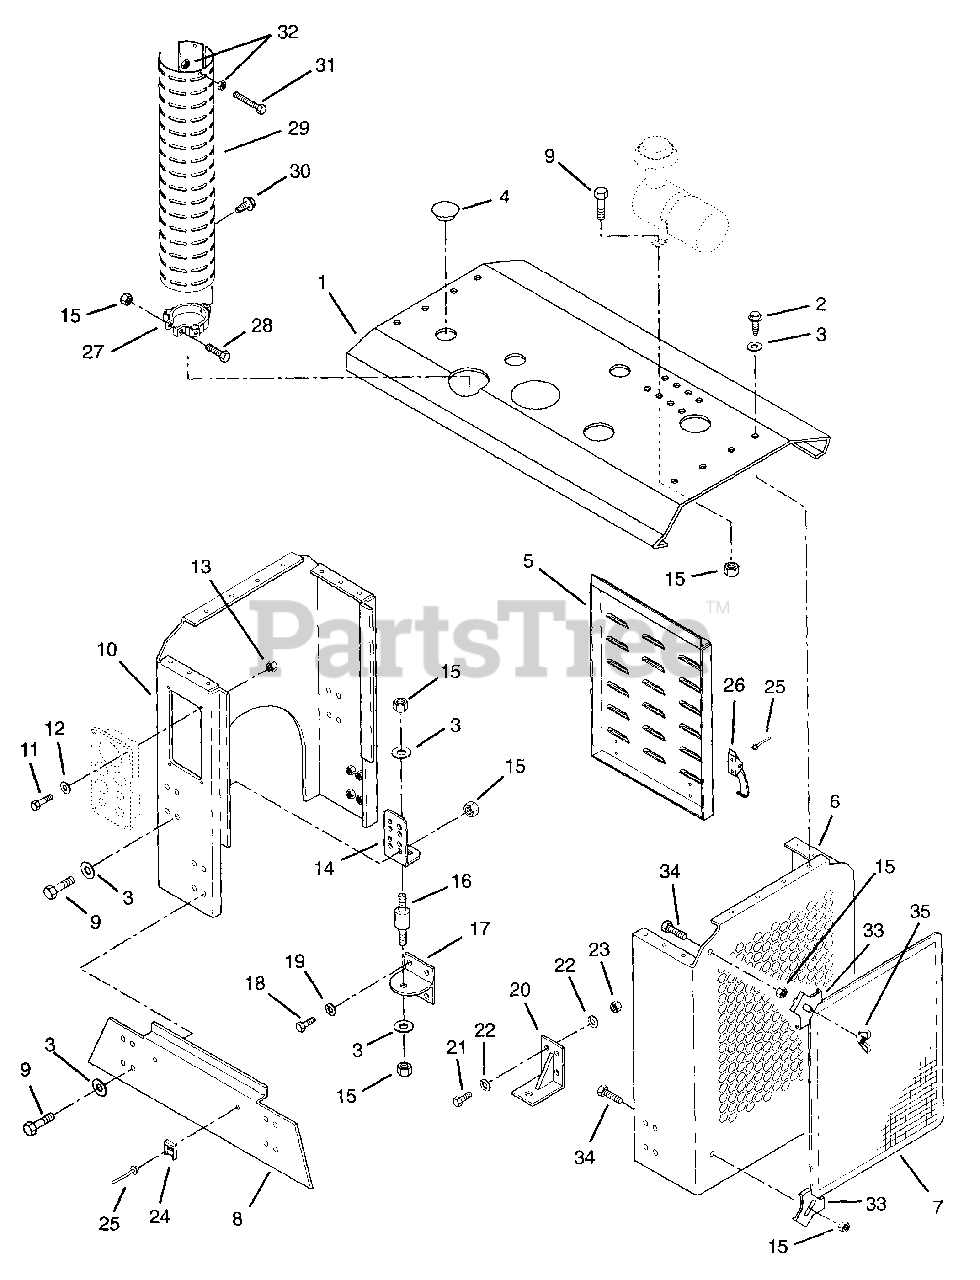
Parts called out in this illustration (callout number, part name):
1	Hood-81HP with Donaldson Air Cleaner
1	Hood-99HP with Donaldson Air Cleaner
1	Hood-108HP with Donaldson Air Cleaner
1	Hood-86HP
1	Hood-110HP
1	Hood-115 HP
2	Screw-Tapping-Hex Washer Head .31-18 x .50
3	Washer-Flat-Steel .38 x .875 x .083
4	Hole Plug
5	Door
6	Front Panel
7	Radiator Screen
8	Side Filler Panel
8	Side Filler Panel-Right Hand
8	Side Filler Panel-Left Hand
9	Bolt-Hex .31-18 x .75 Grade 5
10	Rear Panel
11	Bolt-Hex .25-20 x 1.00 Grade 5
12	Washer-Flat-Steel .312 x .734 x .065
13	Nut-Lock-Center .25-20
14	Outer Support Bracket
15	Nut-Lock-Center .31-18
16	Isolator
17	Inner Support Bracket
18	Bolt-Hex .50-13 x 1.00 Grade 5
19	Washer-Lock .50 x .125
20	Inner Support Bracket
21	Bolt-Hex .38-16 x 1.00 Grade 5
22	Washer-Flat-Steel .438 x 1.00 x .083
23	Nut-Locking-Center .38-16
24	Catch-Over Center Latch
25	Rivet-Pop-Dome Steel .187 x .277
26	Latch-Over Center
27	Clamp-Muffler Guard
28	Bolt-Hex .31-18 x 1.50 Grade 5
29	Guard-Muffler
30	Screw-Tapping-Hex Washer Head .31-18 x .50
31	Bolt-Hex .25-20 x 2.50 Grade 5
32	Nut-Locking-Center .25-20
33	Clip-Screen
34	Bolt-Hex .31-18 x 1.00 Grade 5
35	Nut-Wing-Nylon .312-18
